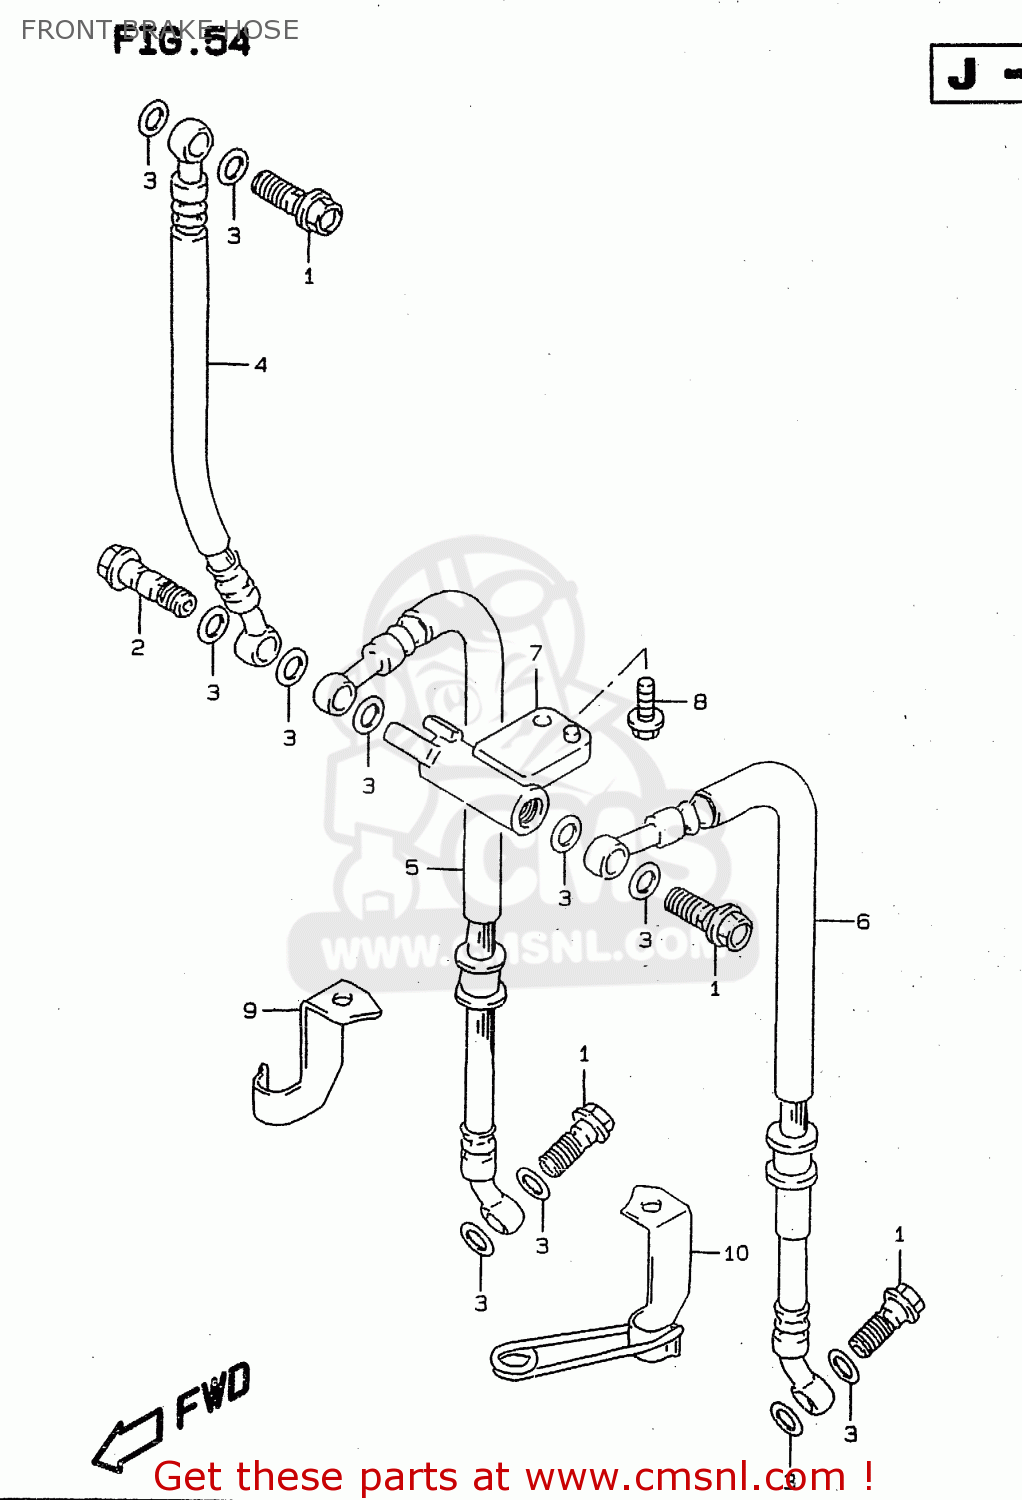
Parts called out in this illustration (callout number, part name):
1	BOLT UNION
2	BOLT UNION
3	WASHER(10X15X1.5)
4	HOSE,FR BRAKE NO.1
5	HOSE,FR BRAKE NO.2,R
6	HOSE,FR BRAKE NO.2,L
7	JOINT,BRAKE HOSE
8	BOLT
9	CLAMP,FR BRAKE HOSE,R
10	CLAMP COMP,FRONT BRAKE
